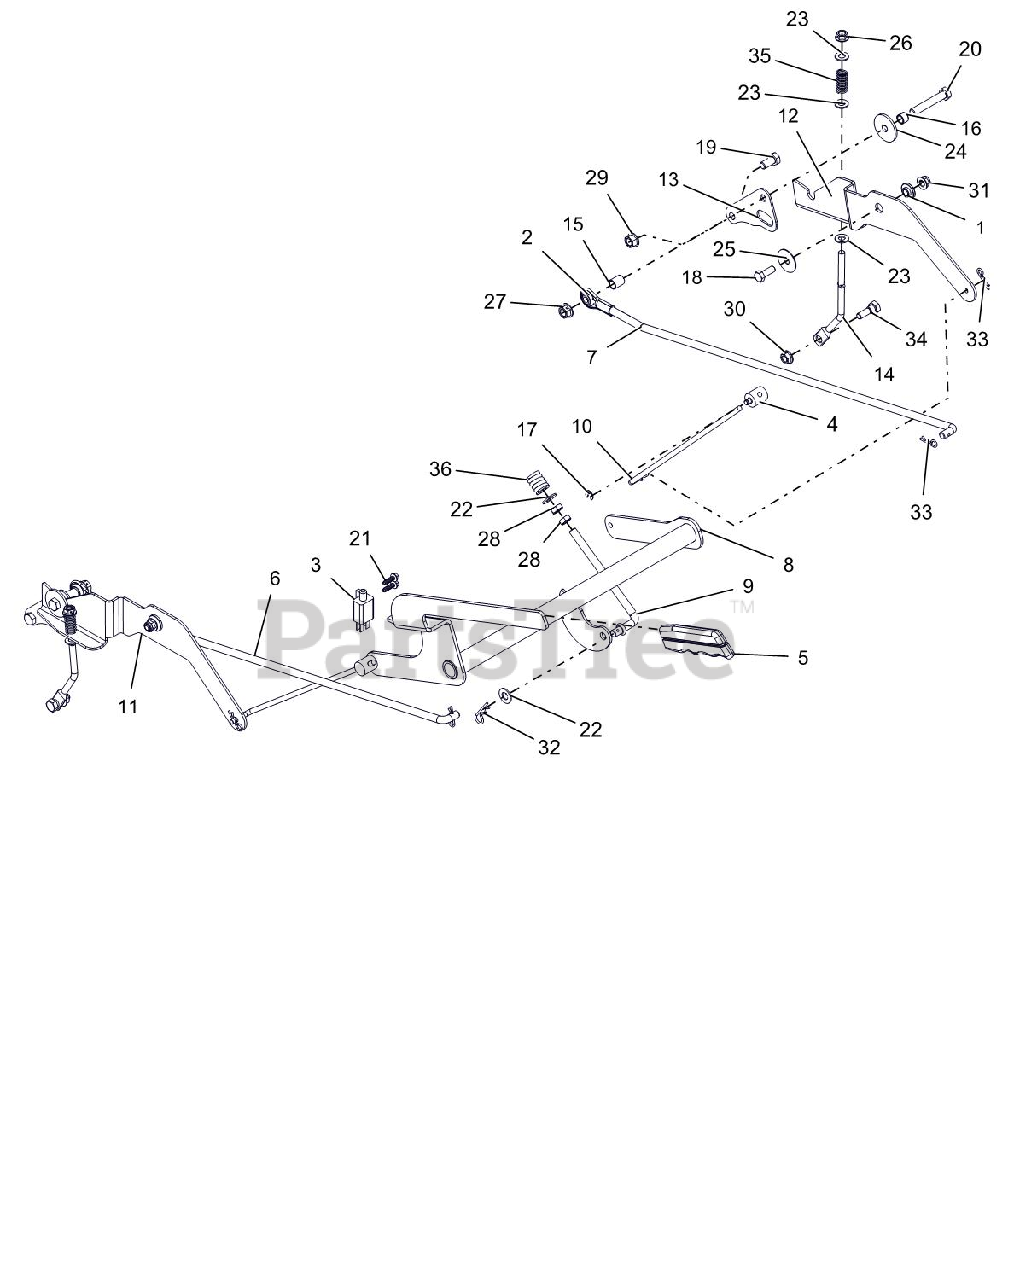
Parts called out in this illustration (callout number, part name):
1	BSHG, FLG .325X.499X.26X.88
2	ROD END, .38 RH
3	SWITCH- DOUBLE POLE N.O./N.O.
4	TRUNION, 1/4-20
5	GRIP, PARKING BRAKE (YELLOW)
6	STEERING, LINKAGE RH
7	STEERING, LINKAGE LH
8	WLDMT, BRAKE LEVER
9	LINK, OVER CENTER, PARKING BRK
10	LINK, BRAKE ARM
11	INTERLOCK, RH BRAKE LINK
12	INTERLOCK, LH BRAKE LINK
13	PLATE, TRANSAXLE ADAPTOR
14	LINK, BRAKE COG
15	SPCR, SLV .385X.500X.652
16	SPCR, SLV .385X.500X.350
17	RG-RTNG-EXT .250X.025
18	BOLT-HEX.31-18X.875 YWZC GR5
19	@BLT-HEX .38-16X.75 GR5 YWZC
20	@BLT-HEX .38-16X2.25 GR5 YWZC
21	SCR-TAP #12X.75 BOSS INDHXHD
22	@WSHR-FL-STL.406X.812X.065 YWZ
23	@WSHR-FL-STL.344X.688X.065YWZC
24	WSHR-FL-STL .380X1.50X.125YWZC
25	WSHR-FL-STL .347X1.254X.048YWZ
26	@NUT-LK-CTR-FLG .31-18 YZ GR F
27	NUT-LK-CTR-FLG .38-16 YWZC
28	NUT-HEX-JAM .375-16 YWZC
29	@NUT-LK-TOP-FLG .38-16 YWZC
30	@NUT-LK-TOP-FLG .31-18 YWZC
31	@NUT-LK-NYL-FLG .31-18 YWZC
32	PIN-HAIR CTR .09 X 1.50 YWZC
33	PIN-HAIR INT .08X.18X1.18 YWZC
34	BOLT,SHLDR .38X.25 -.31-18X.75
35	SPRING, COMPRESSION
36	SG-COMP .187X.56X1.62
